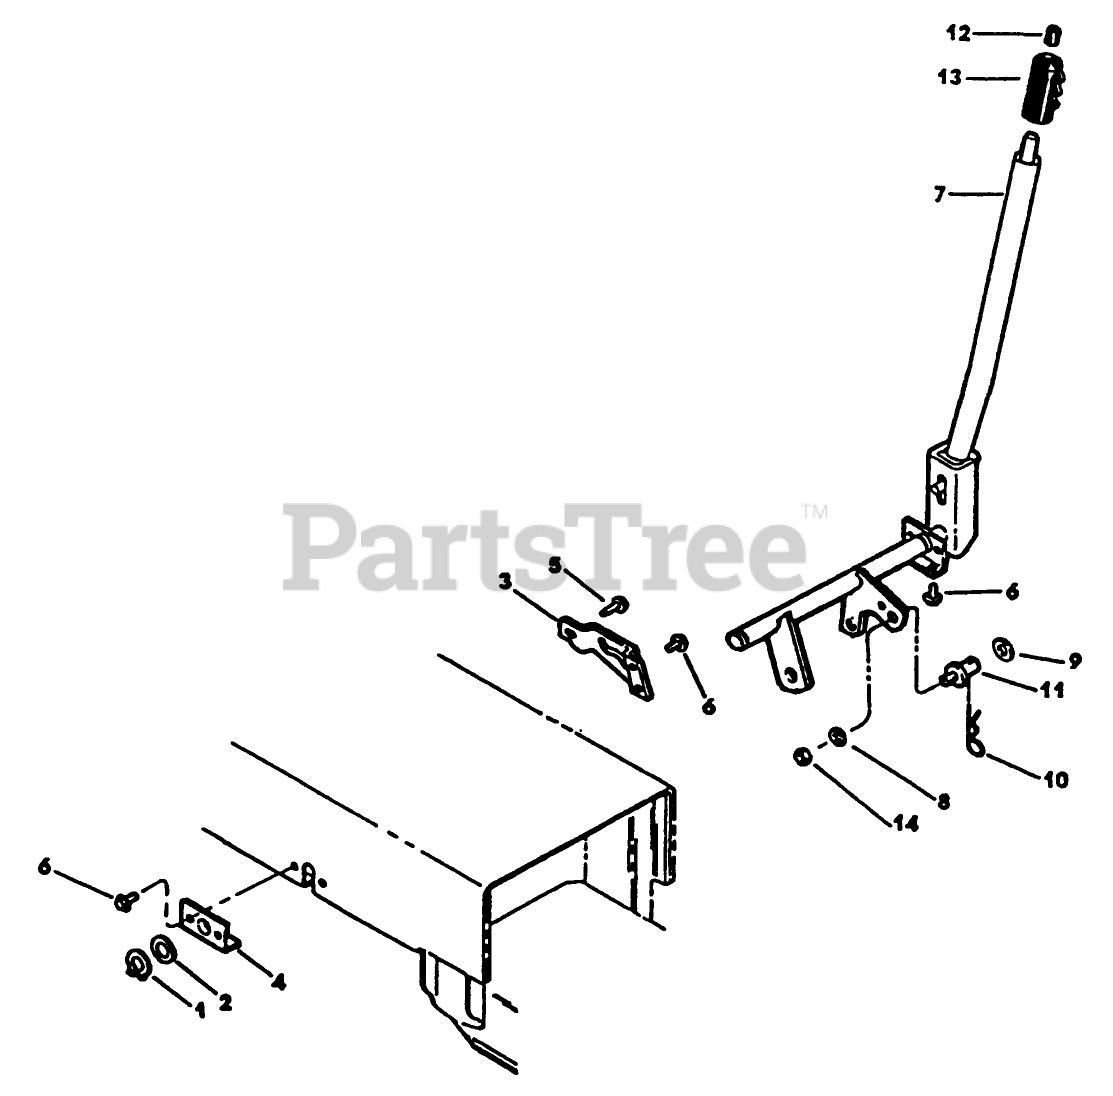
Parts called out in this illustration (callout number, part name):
1	RING-RETAINING
2	WASHER
5	SCREW
8	WASHER
10	PIN-HAIR
12	TIP-ROD
14	NUT
